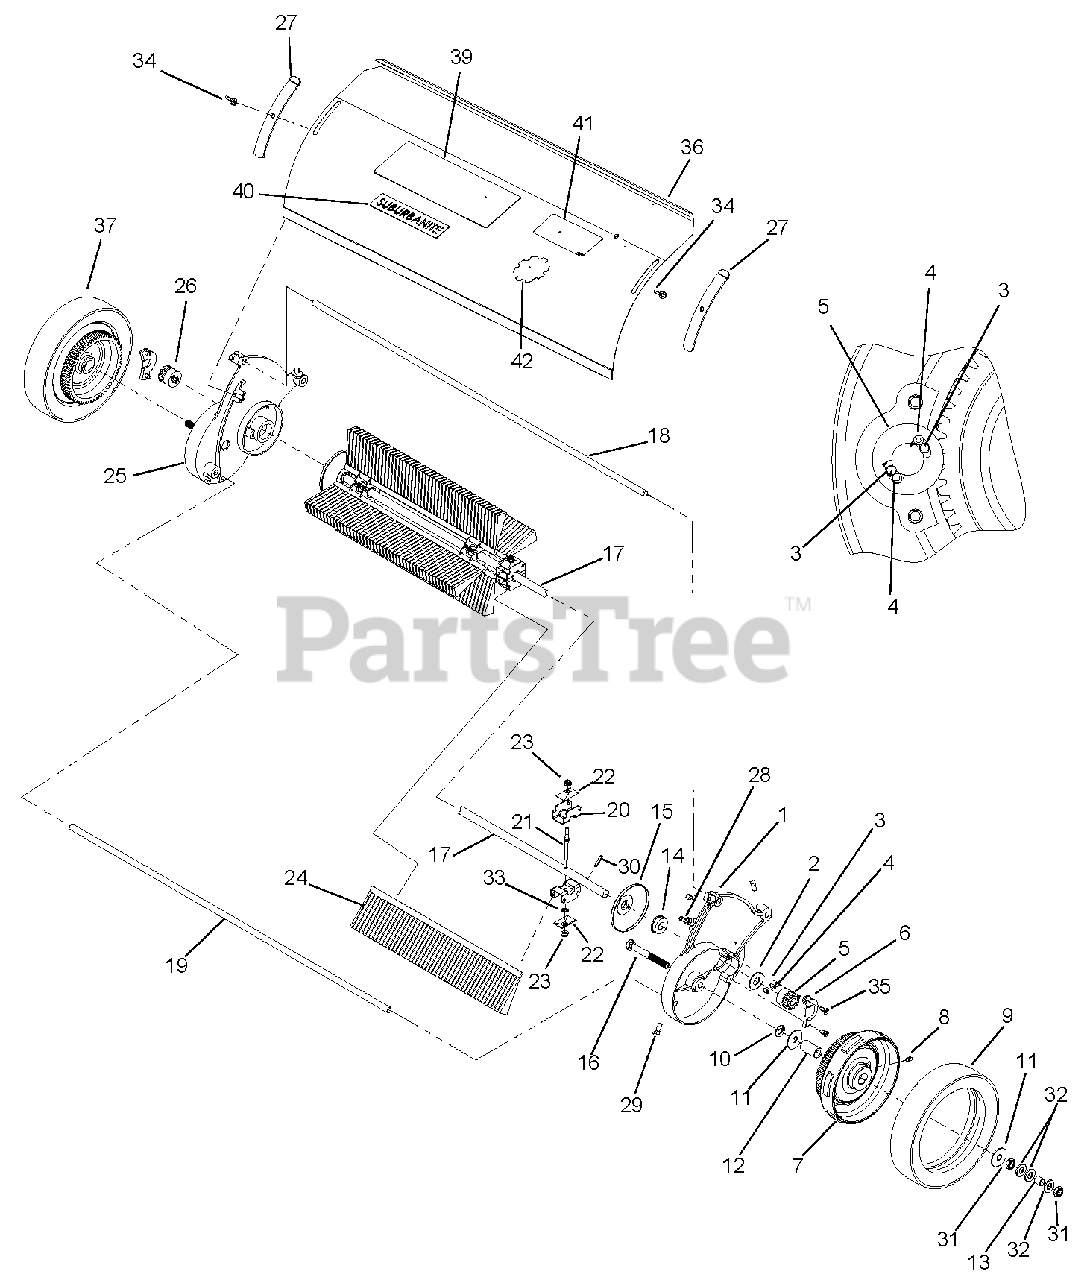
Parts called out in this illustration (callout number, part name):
1	Side Plate, Left Hand
2	Washer, Flat .656 x 1.50 x .06
3	Pin, Dowel .1875 OD x .4375
4	Spring, Pawl .188 x .049 x .438
5	Pinion, Left
6	Casting, Cover Pinion
7	Wheel Hub, Drilled
8	Grease Fitting, 3/16
10	Washer, Fiber
11	Washer, Flat .516 x 1.625 x .075
13	Spacer, Axle
14	Bearing, Flange Radial
15	Dust Cover, Wheel Hub
16	Bolt, Axle 1/2-20 x 4 Special Grade 2, 1-7/8 Thread
17	Reel Shaft, Plated
18	Tie Rod, Top
19	Tie Rod, Front
21	Plated Stud, Zinc
22	Clamp, Brush Strip
23	Nut, Flange Lock .25-20 YWZC
24	Brush, Sweeper
25	Side Plate, Right Hand
26	Pinion, Right
27	Clamp, Hood
28	Bolt, Hex .31-18 x 1.00 Grade 5 YWZC
29	Set Screw, Square Head
30	Roll Pin, 3/16 x 1-3/4
31	Nut, Jam Nylock 1/2-20 Grade 2 YWZC
32	Washer, Flat Steel .531 x 1.06 x .095 YWZC
33	Nut, Speed 1/4
34	Nut, Wing 5/16-18 Steel Plated
35	Screw, Flat Head 1/4-20 x 5/8
36	Hood with Decals
37	Sweeper Tire/Wheel Assembly (includes items 7, 8 & 9)
38	Pinion Kit (includes items 3, 4, 5 & 26)
39	Decal, Gravely Logo
40	Decal, Suburbanite
41	Decal, Danger Read Manual
42	Decal, Gravely, Heritage Small
